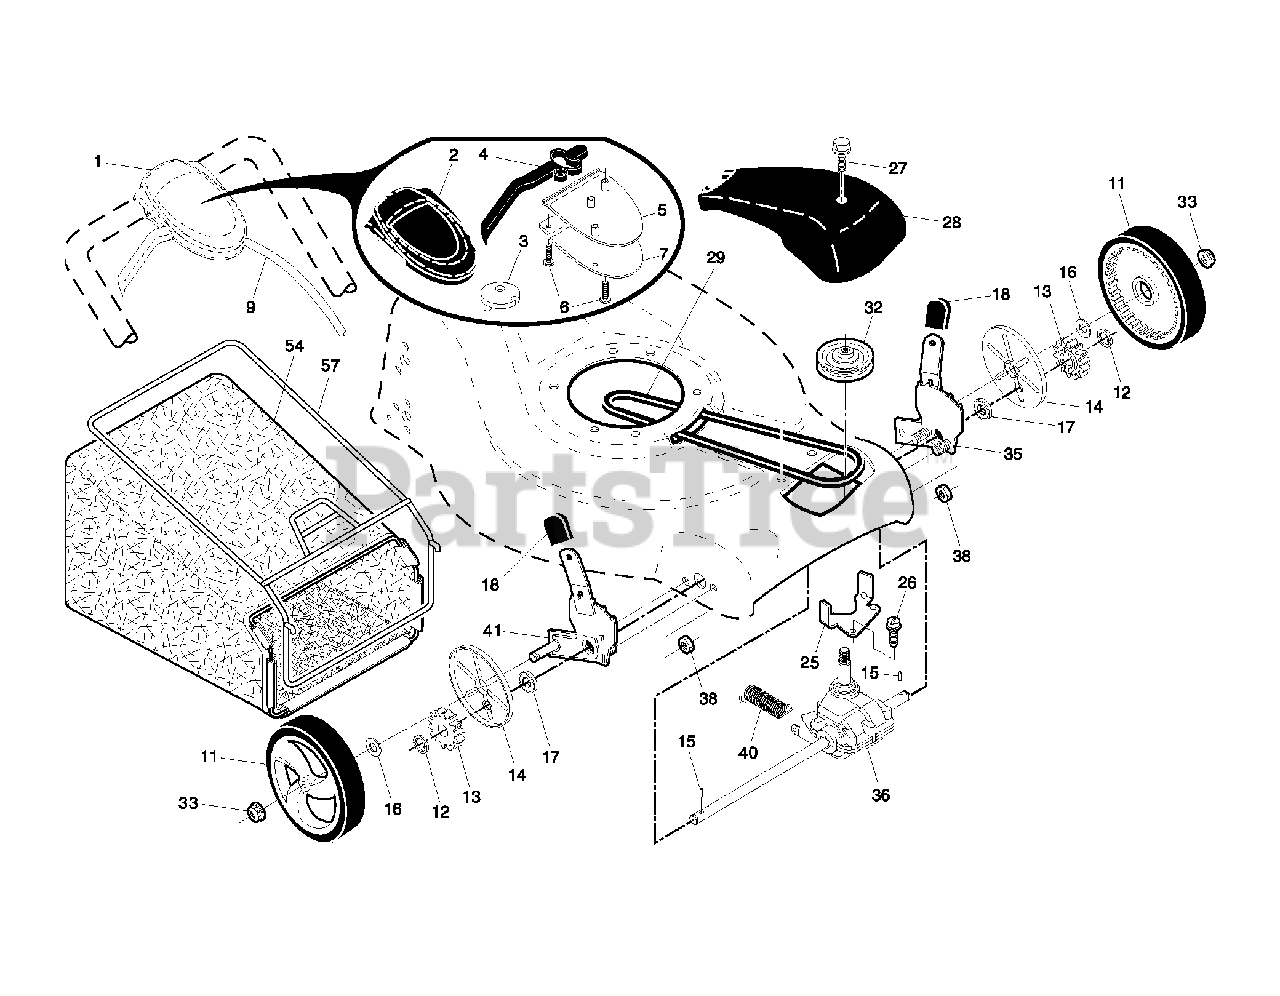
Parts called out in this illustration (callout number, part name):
2	COVER, TOP DRIVE CONTROL
3	PULLEY.CAM.DRIVE.CONTROL.EZ
5	COVER BOTTOM DRIVE CNTRL BLACK
6	SCREW, PHILLIPS HEAD 10 X 5/8
7	BRACKET.DRIVE.CONTROL.MOUNT
9	CABLE ASSEMBLY, DRIVE
12	E-RING 7/16 RE
13	PINION.14.TEETH.FGD
14	COVER.DUST.WHEEL
15	PAWL, DRIVE
16	WASHER FLUT
17	BEARING
18	SELECTOR KNOB
25	BELT KEEPER
27	SCREW, HEX HD TAPPING #10-24 1
29	BELT.DRIVE.FG
32	RP PULLEY.DRIVE.EZ
33	NUT.HEX.FLANGE.3/8-16.LOCKNUT
35	RP KIT, WHEEL ADJUSTER, LH
36	TRANSMISSION.21.FGD.HT.VST
38	LOCKNUT
41	KIT, WHEEL ADJUSTER, RH
57	FRAME.GBAG.21.FWGD
